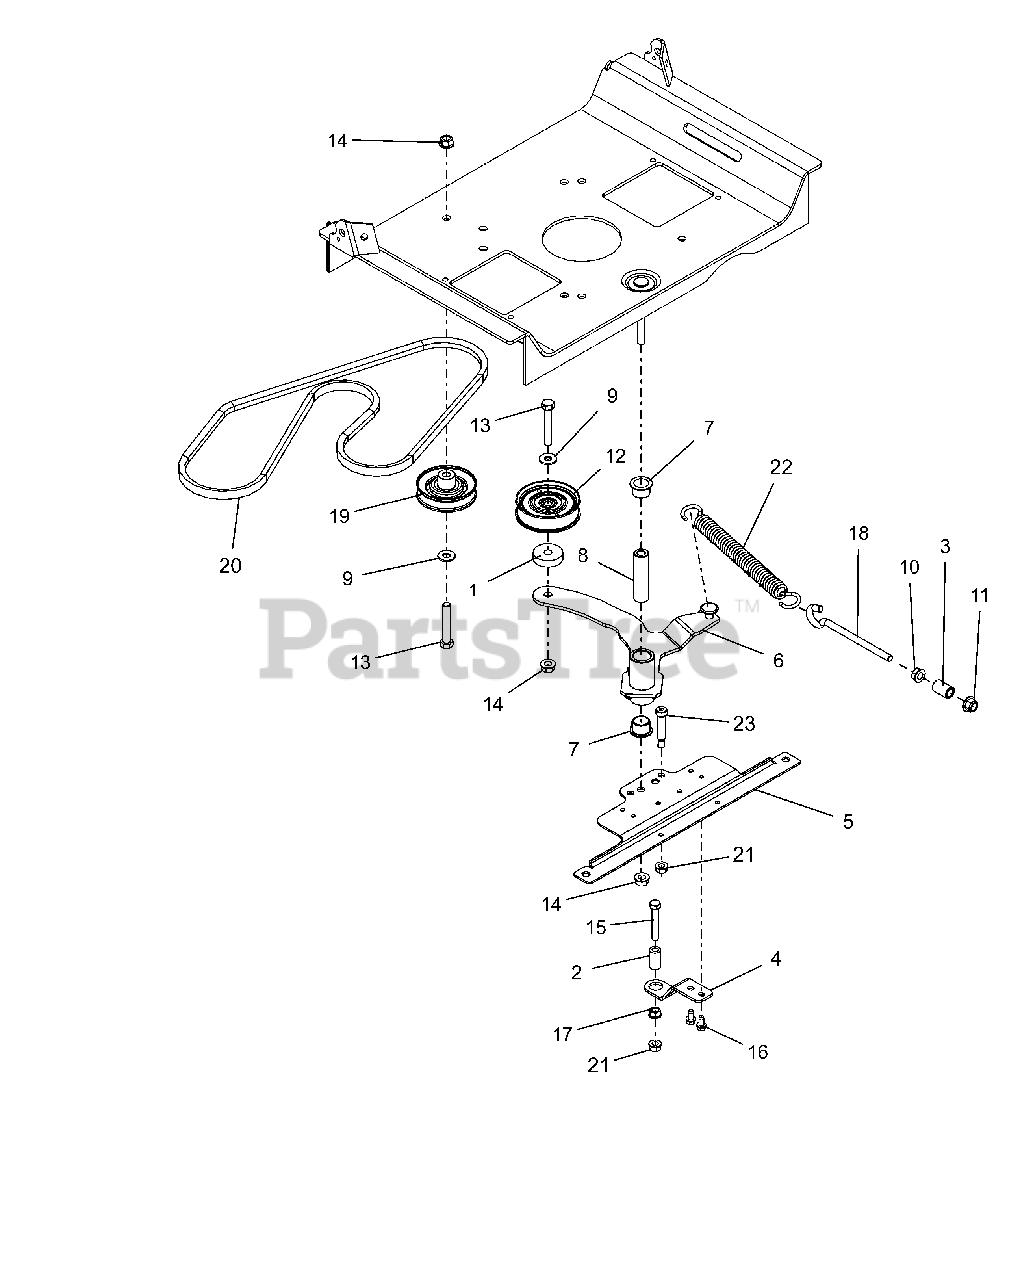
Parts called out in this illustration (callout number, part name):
1	SPACER, .39 X 1.50 X .380
2	SPACER, RUBBER 5/16 IDX1.0 LG
3	SPACER, .375X.625X.970 (PM)
4	BRKT, CLUTCH STOP (XL)
5	BRKT, DRIVE IDLER MOUNTING
6	WLDMT,GRD DRIVE IDLER ARM-LGR
7	BSHG-FLG 0.75X0.875X.625X1.125
8	BUSHING, SLEEVE .38X.750X2.78
9	WSHR,FLT .375X.875X.083 ZCC
10	NUT, SPNLK-FLG .38-16 G5 ZCC
11	NUT,NYL-FLG .38-16 GF ZCC
12	IDLER, FLAT - 3.05" X .75"
13	BLT,HEX .38-16X2.25 G5 ZCC
14	NUT-LK-TOP-FLG .38-16 ZC120
15	BLT, HEX .31-18X2.00 G5 ZCC
16	SCR-TAP .25-20X.50 HWH ZCC
17	NUT,SPNLK-FLG .31-18 G5 ZCC
18	BOLT,.38-16 X 4.25-.62 DIA EYE
19	IDLER, V-3.000 OD
20	V-BELT, A-RAW EDGE
21	NUT-LK-TOP-FLG .312-18 GF ZCC
22	SPRING, EXTENSION
23	BLT-SHLDR .38X1.5X.31-18 SLT Y
